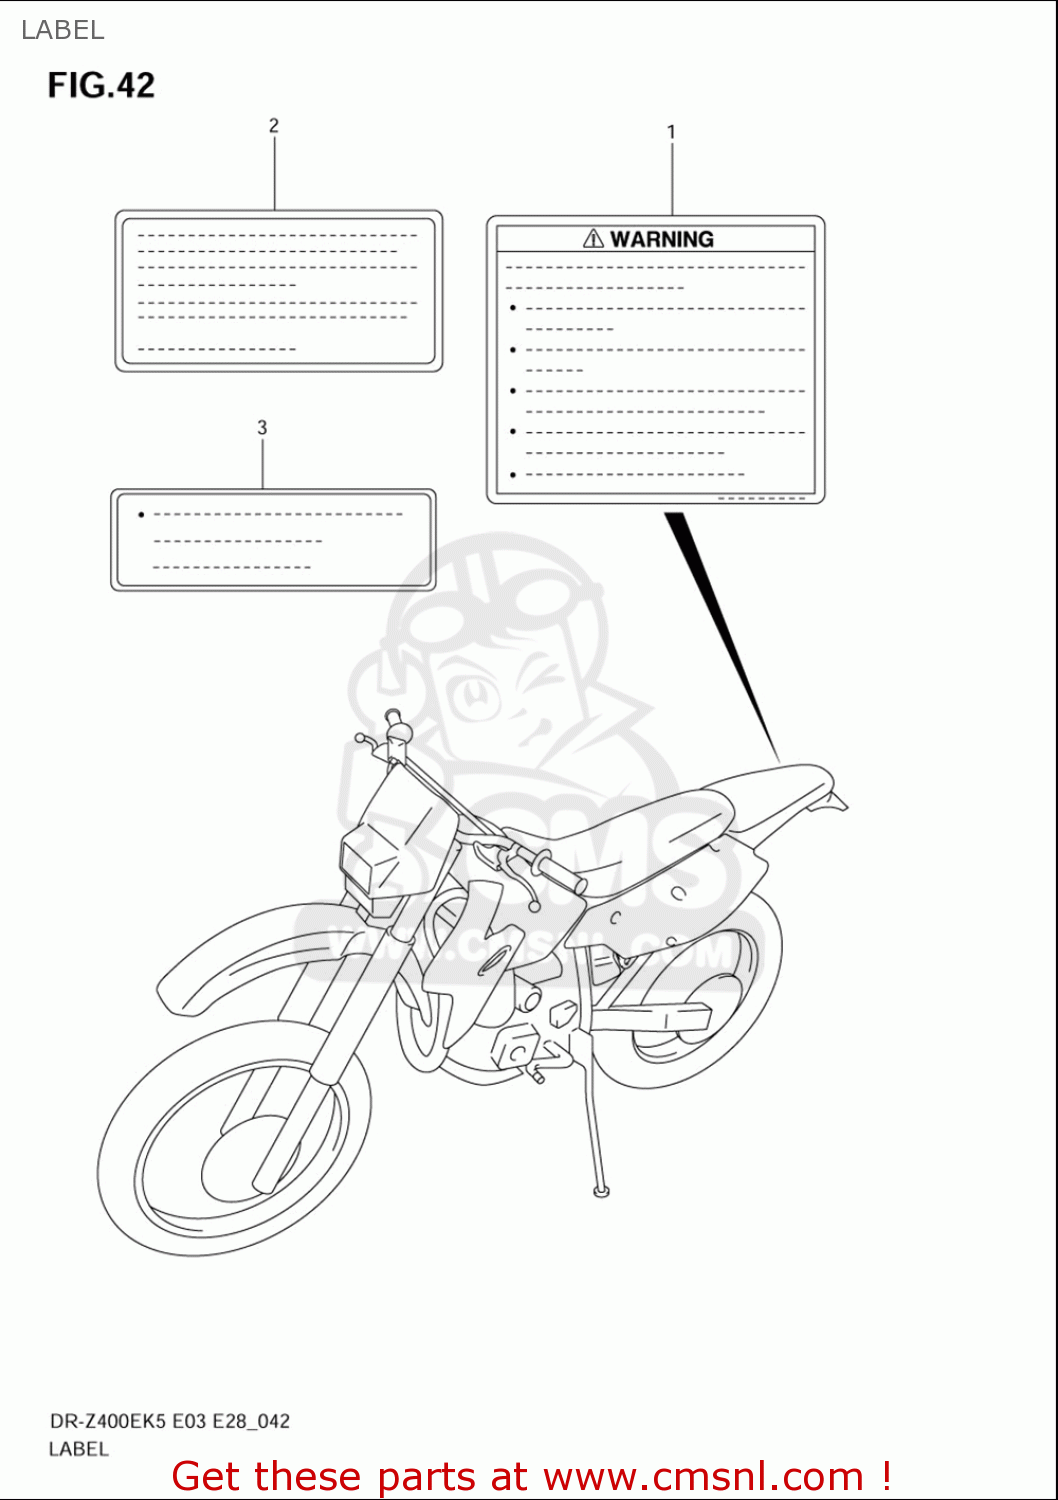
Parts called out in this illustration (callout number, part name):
1	LABEL,GENERAL WARNING
2	LABEL,MANUAL NOTICE
3	LABEL,FUEL INFORMATION
4	MANUAL,OWNER'S
